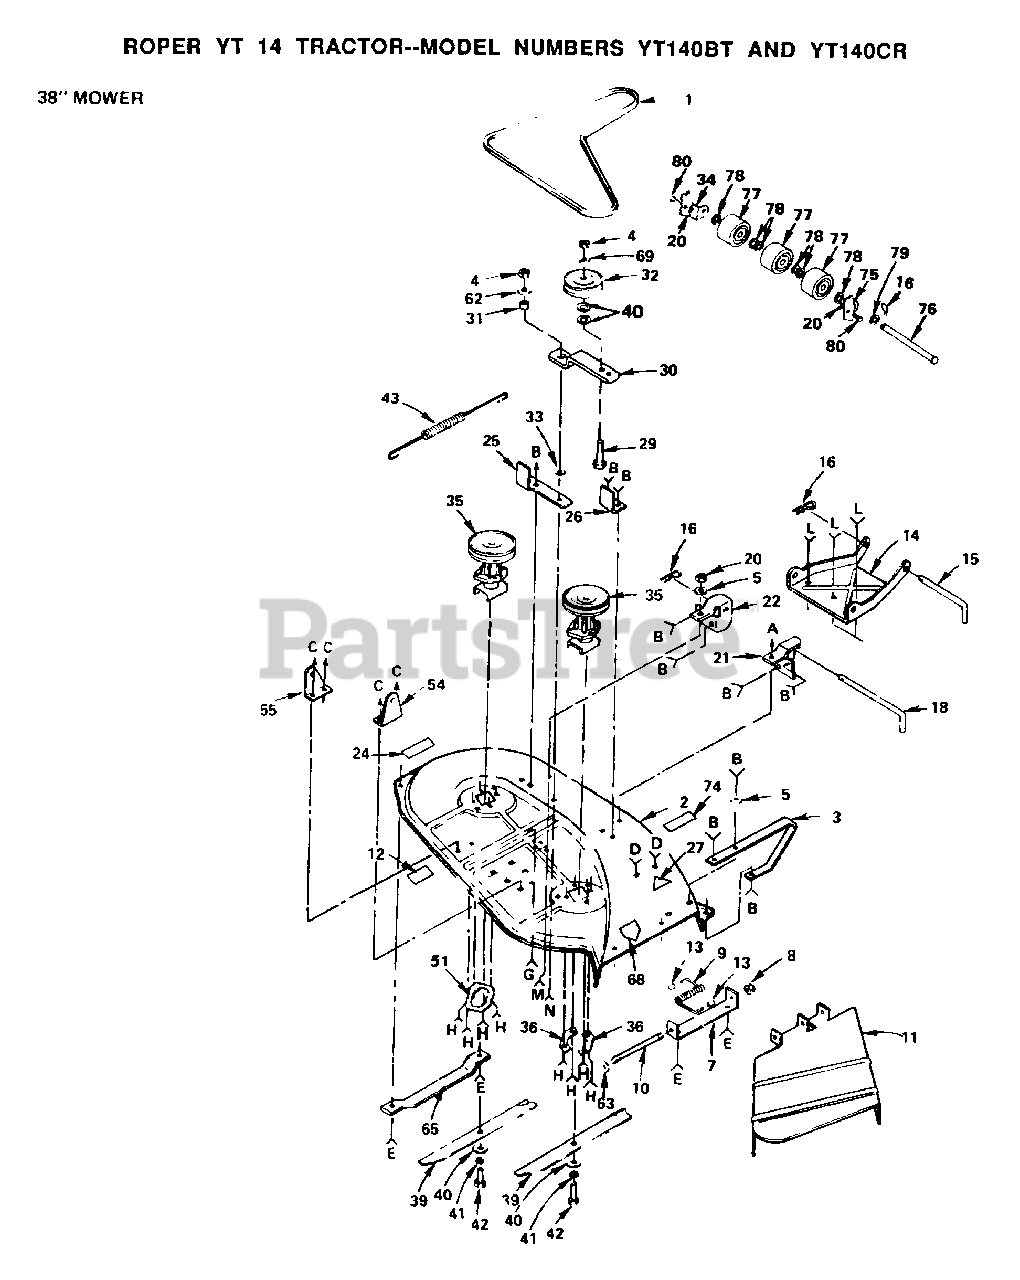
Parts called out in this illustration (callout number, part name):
1	BELT-V.79.1.MWR
5	WASHER M
10	ROD-HINGE T
11	DEFLECTOR-SHLD T
13	CAP-SLEEVE LT
14	LINK.PARALLEL
15	"ROD, FRT. PARAL T"
16	SPRING.RETAINER
18	HINGE PIN T
21	BRACKET RH LT
22	BRACKET LH T
24	DECAL INSTRUCTION CAUTION
25	SUPPORT ARM T
26	STOP T
27	DECAL - SAFETY STANDARD
31	SPACER RETAINER
32	IDLER-FLAT T
33	"WASHER, WEAR LT"
34	BRACKET LH T
36	SUPPORT PLATE LT
40	WASHER
42	BOLT.3/8-24X1-1/2
43	"SPRING.EXT.8.5"""
51	SUPPORT T
54	"BRKT,SUSP RH T"
55	"BRKT,SUSP REAR LH"
63	WASHER
65	RUNNER-LH M
69	WASHER
74	DECAL.WARNING.T
75	BRACKET RH T
76	PIVOT PIN T
77	ROLLER T
78	WASHER T
80	BOLT
